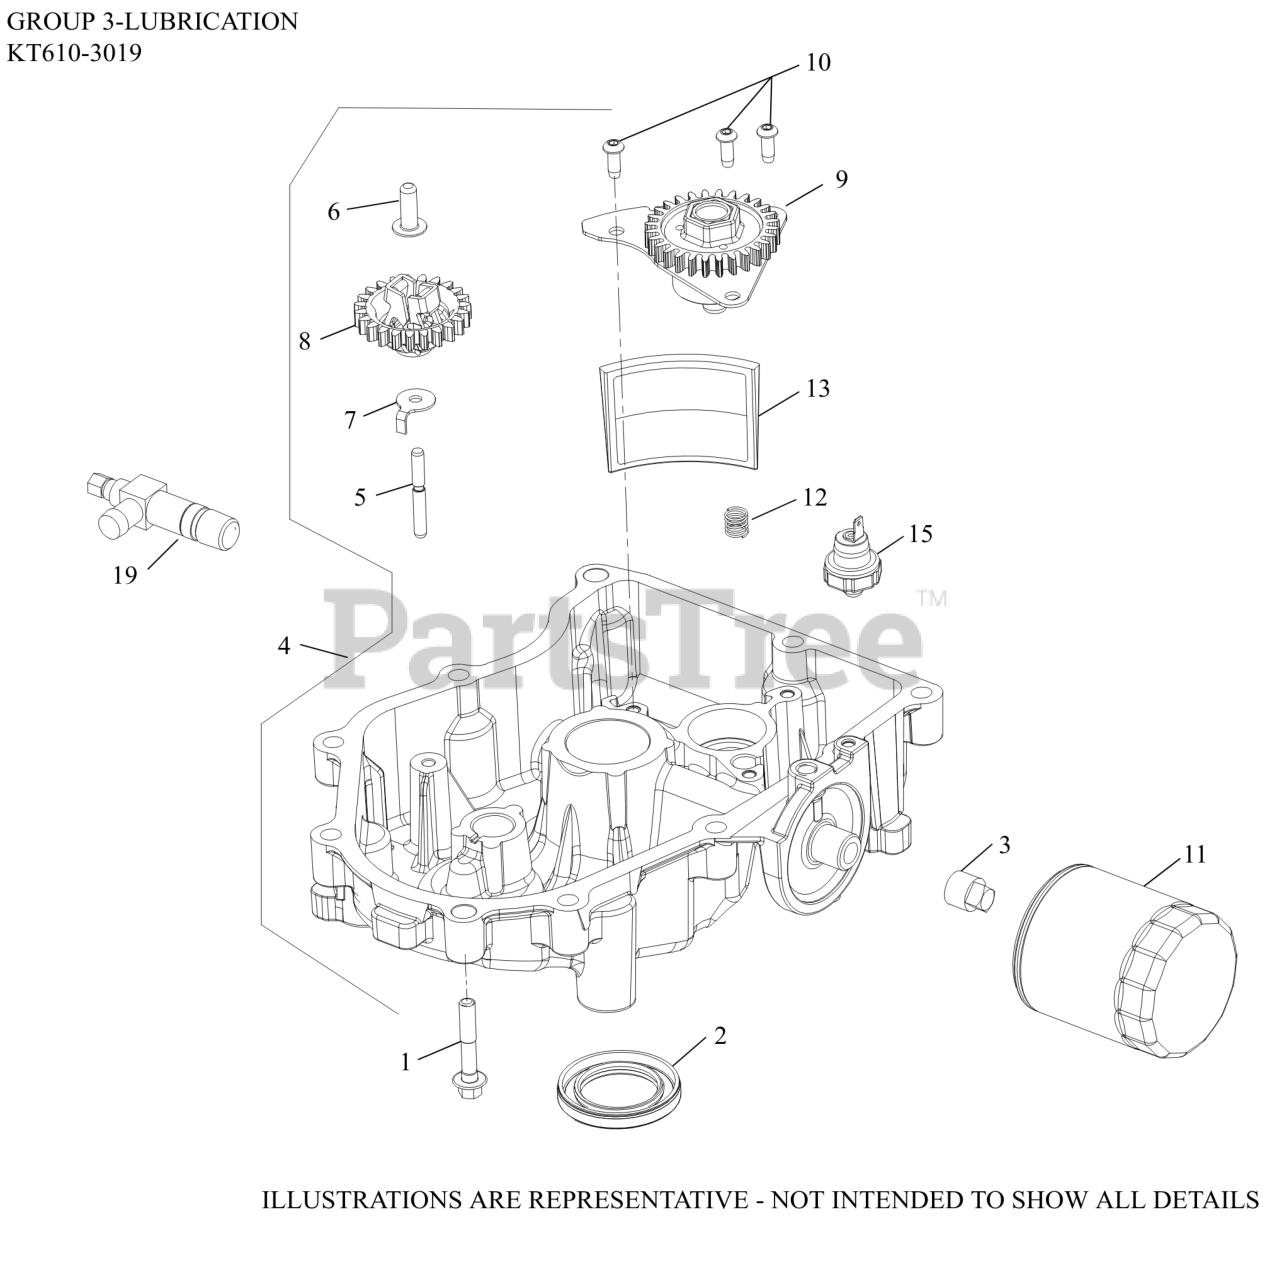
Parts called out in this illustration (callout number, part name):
1	SCREW, FLG M8X1.25X45
3	PLUG, SQ HD PIPE 3/8"
4	PAN ASSEMBLY, OIL-(#3219924S)
5	SHAFT, GOVERNOR GEAR
6	PIN, GOVERNOR REGULATING
7	TAB, LOCKING
8	KIT, GOVERNOR GEAR
9	PUMP ASSEMBLY, OIL
10	SCREW, BUTTON HEAD
11	OIL FILTER
12	SPRING, COMPRESSION
13	SCREEN, OIL
15	SENSOR, OIL PSI 3 TERMINAL
19	VALVE, OIL DRAIN MEDIUM
